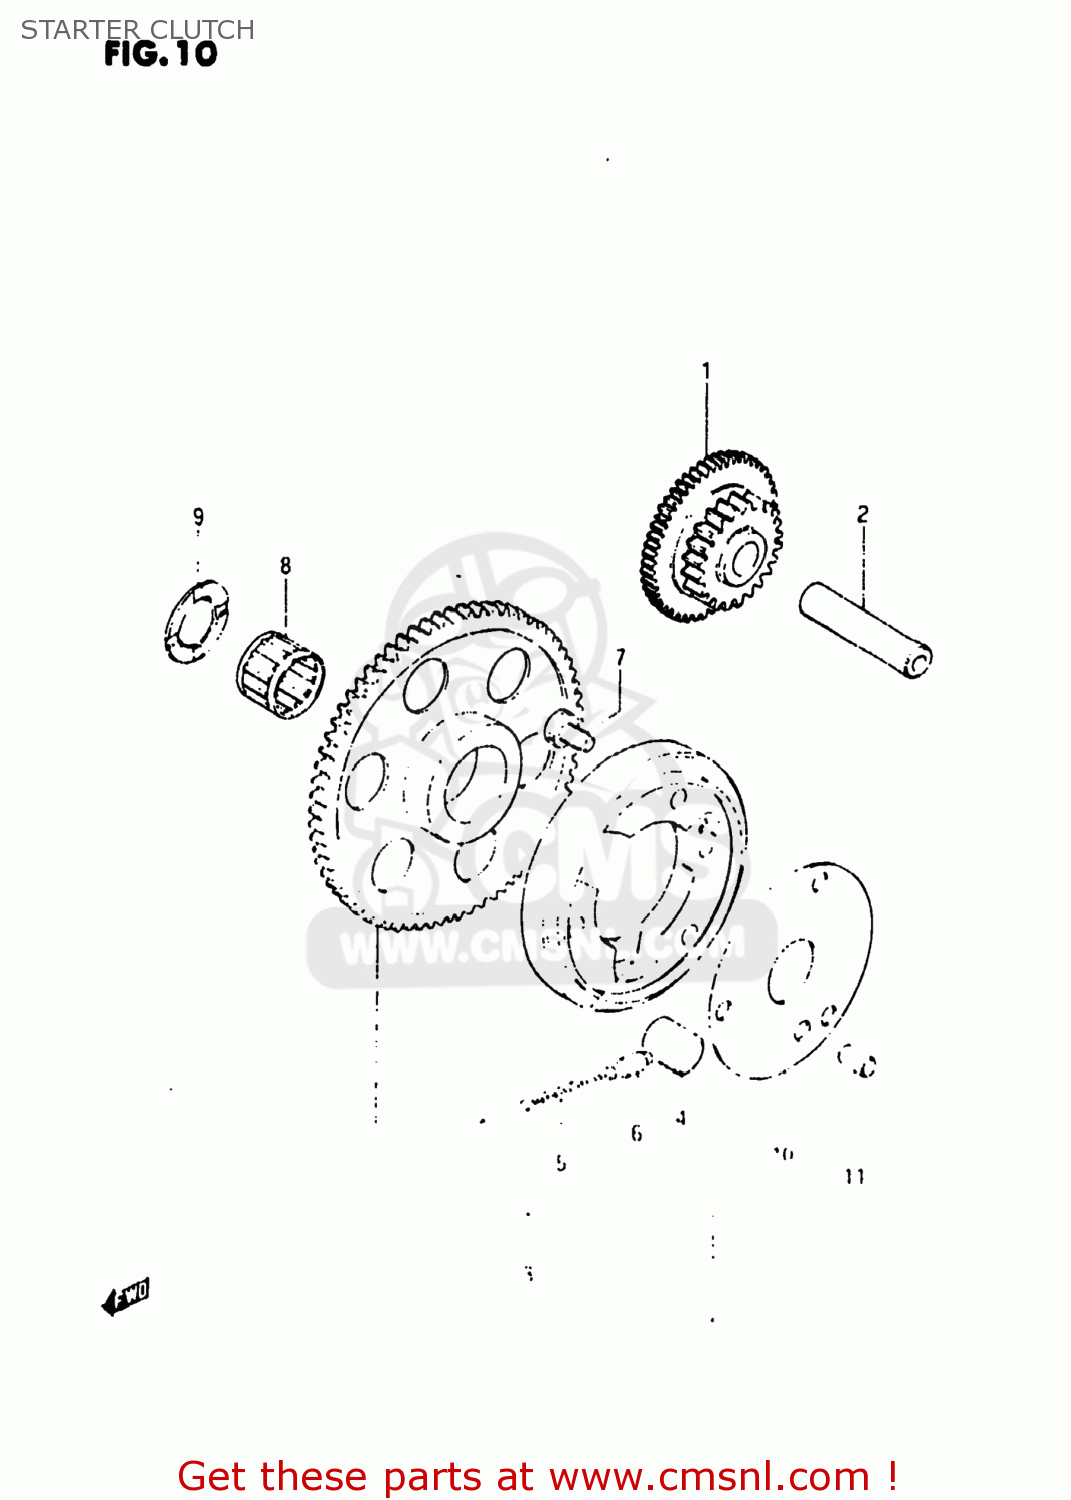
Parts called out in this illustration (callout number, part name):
1	GEAR,STARTER IDLE
2	PIN(7.4X13X56)
3	CLUTCH SET,STARTER
4	ROLLER(15X13)
5	SPRING
6	PIECE,PUSH
7	BOLT
8	BEARING(29X35X24)
9	WASHER(29X41X2.5)
10	SHIM,STARTER CLUTCH HUB
11	PIN
